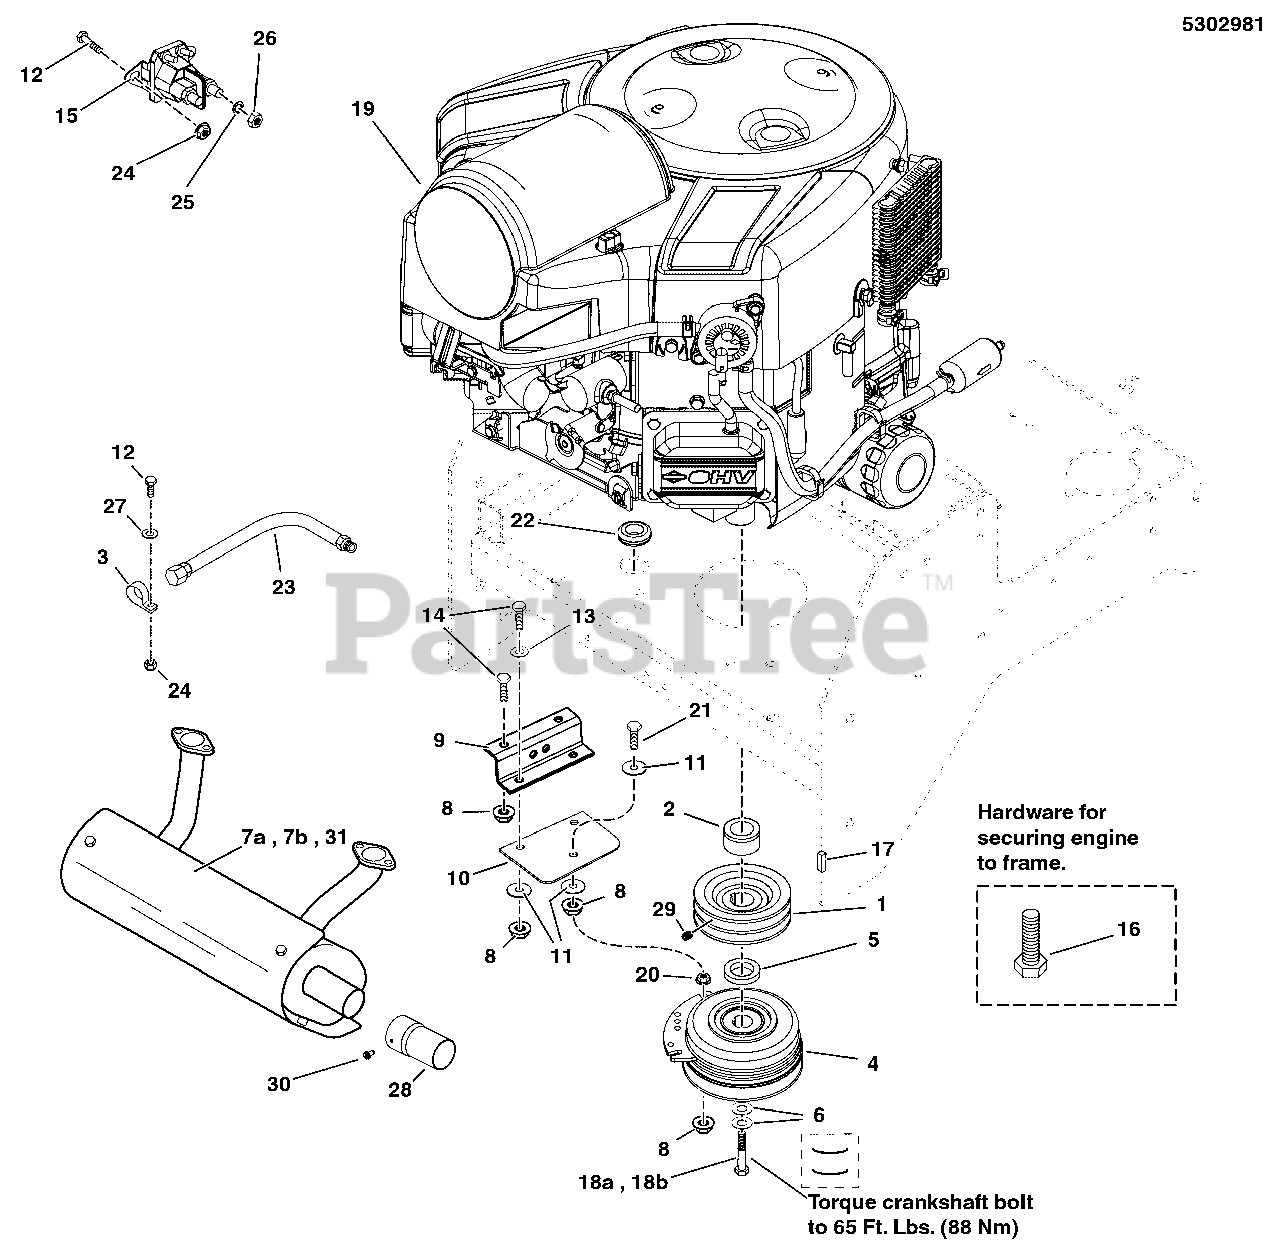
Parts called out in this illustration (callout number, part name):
1	PULLEY, CRANKSHAFT (DOUBLE A)
2	SPACER, 1.13 X 1.75 X 1.09, PM
3	CLAMP, VINYL INSULATED
4	* CLUTCH, 5218-134, WARNER
5	SPACER, 1.13 X 1.75 X .50
6	BELLEVILLE WASHER 1.1875 X .442 X .089
8	NUT, 5/16-18 HEX NYLOCK FLANGE
9	ANCHOR, CLUTCH - BLK
10	CLUTCH ANCHOR PAD
11	WASHER, .34 X 1.25 X 10 GA
12	BOLT, 1/4-20 X 3/4 GD5 YZ
13	WASHER, 5/16" SAE
14	BOLT, 5/16-18 X 1 GD5 YZ
15	SOLENOID-4 POLE 12 VOLT DC (TROMBETTA)
16	BOLT, 5/16-18 X 1-3/4 GD5 YZ
17	KEY, 1/4 SQ. X 1.00
19	** ENGINE, B&S, COMM TURF
20	NUT, 5/16-18 HEX SERRATED FLANGE (LARGE)
21	BOLT, 5/16-18 X 2-1/4 TFL, GD5 YZ
22	GROMMET, 7/8
23	HOSE-OIL DRAIN .375ID 16.5L
24	NUT, 1/4-20 HEX SERRATED FLANGE
25	WASHER, Light Lock, 5/16
26	NUT, Hex Jam, 5/16-24
27	WASHER, 1/4 SAE
28	EXTENSION, TAILPIPE, 3" - BLACK
29	SET SCREW, 5/16-18 X 3/8, KNURL
30	SCREW,SELF-TAP,#8-32 X 3/8,WASH HEX, CZ
31	MUFFLER, RIGHT OUTLET ASSY
